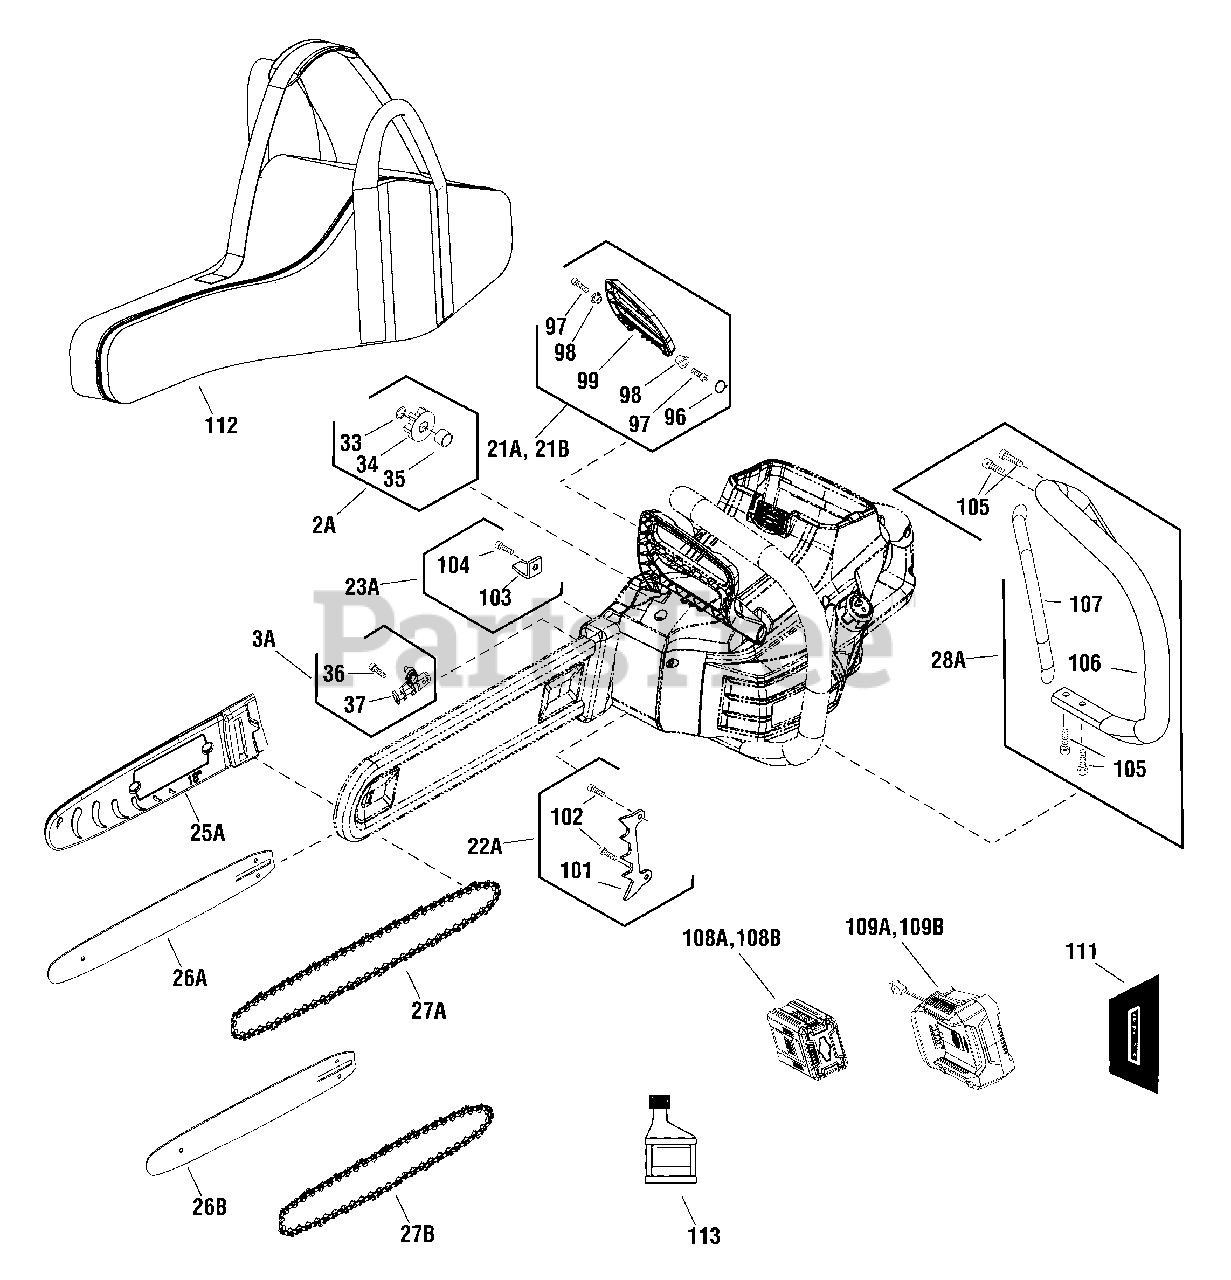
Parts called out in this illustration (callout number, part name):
2A	KIT, SPROCKET ASSEMBLY
3A	KIT, CHAIN SAW TENSION ASSEMBLY
21A	KIT, FRONT HAND GUARD ASSEMBLY, NA
21B	KIT, FRONT HAND GUARD ASSEMBLY, EU
22A	KIT, BUMPER SPIKE ASSEMBLY
23A	KIT, CHAIN BLOCK
25A	KIT, BAR COVER
26A	KIT, BAR, 18"
26B	KIT, BAR, 12"
27A	KIT, CHAIN, 18"
27B	KIT, CHAIN, 12"
28A	KIT, FRONT HANDLE ASSEMBLY
33	CIRCLIP
34	SPROCKET
35	SPACER, BUSHING
36	SCREW
37	TENSIONER, Chain
96	SPRING, Torsion
97	SCREW
98	BUSHING
99	HANDGUARD, FRONT
101	BRACKET, BUMPER SPIKED
102	SCREW
103	BRACKET, CHAIN BLOCK
104	SCREW
105	SCREW
106	HANDLE, FRONT
107	PAD
108A	* BATTERY, 2.0, 82V NA
108B	* BATTERY, 2.0, 82V EU/AU
109A	* CHARGER, Battery, NA
109B	* CHARGER, Battery, EU
111	DECAL, Charger
112	CASE, CARRYING, CHAINSAW
113	OIL, CHAINSAW
